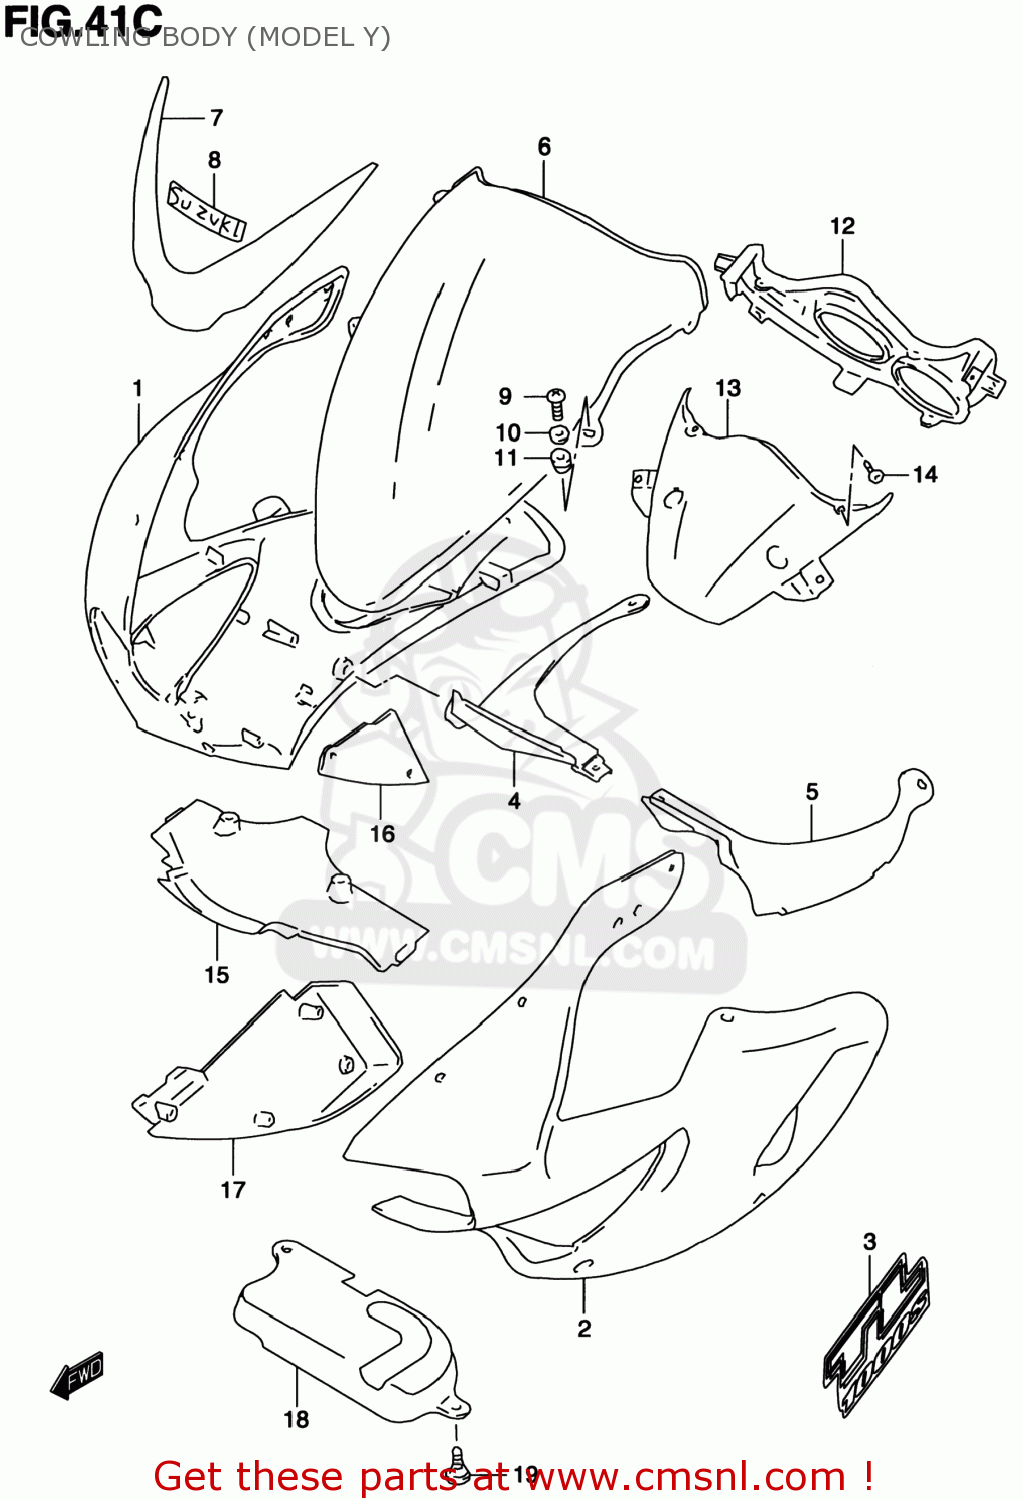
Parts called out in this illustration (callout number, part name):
1	COWLING,SIDE,R(RED)
2	COWLING COMP,SIDE,LEFT
3	EMBLEM,COWLING SIDE
4	PANEL,SIDE,R
5	PANEL,SIDE,L
6	WINDSCREEN(SILVER)
7	TAPE,WINDSCREEN
8	EMBLEM,SUZUKI
9	SCREW(5X14)
10	WASHER
11	NUT
12	PANEL,METER
13	PANEL,FR
14	CLIP(BLACK)
15	COWLING,CTR LWR
16	COWLING,INNER,R
17	COWLING,INNER,L
18	COVER,COWLING FR LWR
19	BOLT
